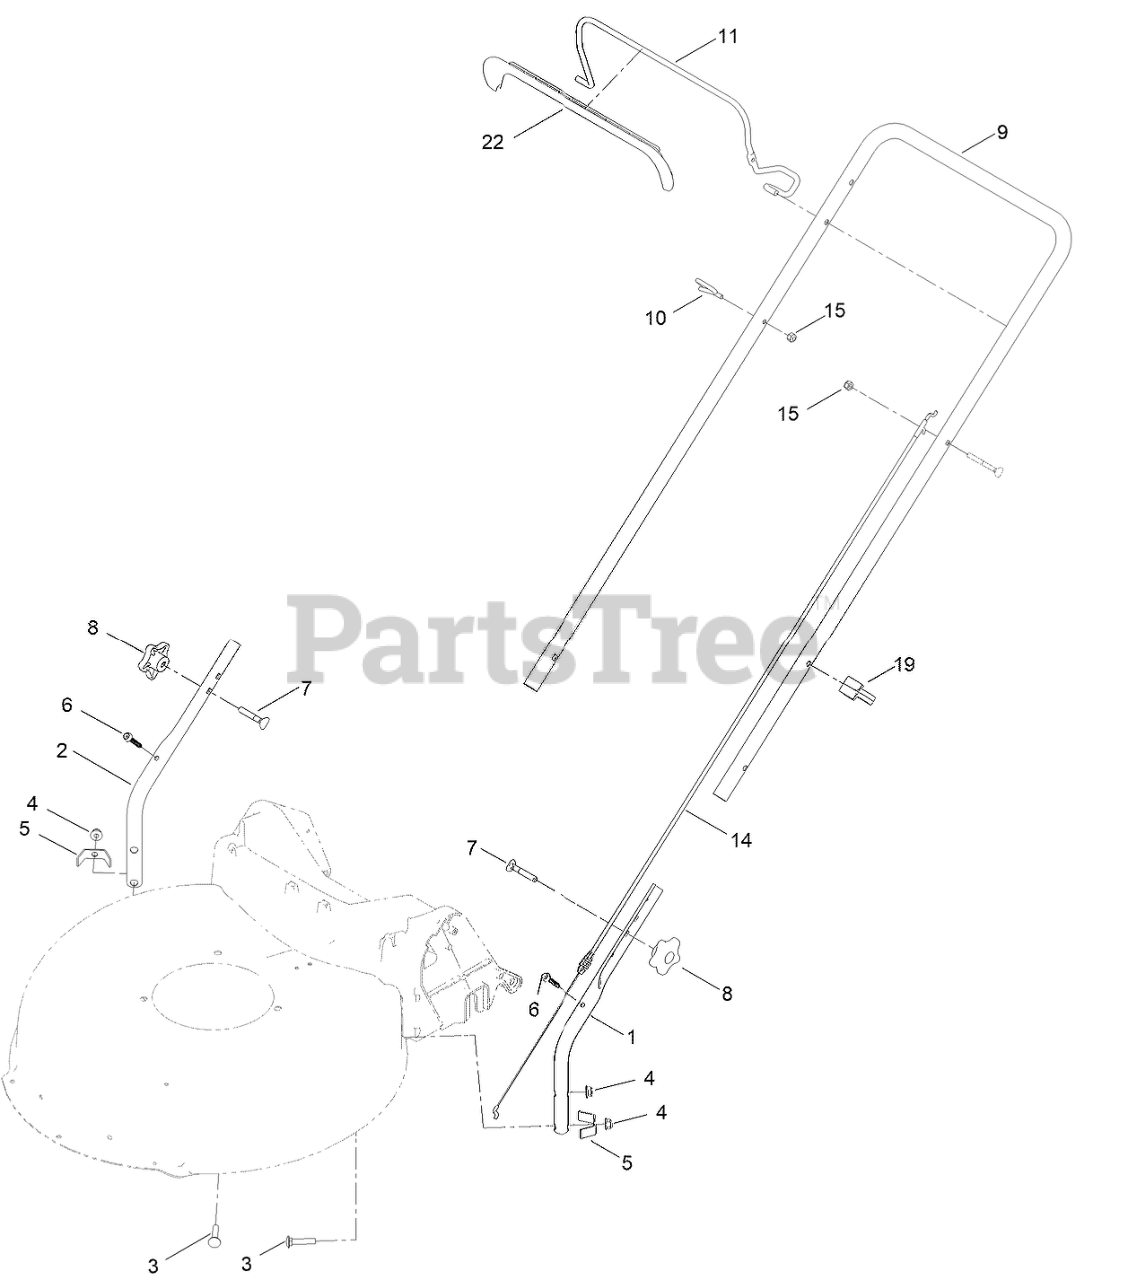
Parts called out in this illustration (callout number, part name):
1	HANDLE-LOWER, LH
2	HANDLE-LOWER, RH
3	BOLT-CARR
4	NUT-FLANGE, NI
5	BRACKET-CHUTE
6	SCREW-FLANGE, SERRATED
7	SCREW-HANDLE
8	KNOB-HANDLE
9	HANDLE-UPPER
10	GUIDE-ROPE
11	BAIL-BRAKE
14	CABLE-BRAKE, ENGINE
15	NUT-LOCK, NI
19	GUIDE-CABLE
22	COVER-BAIL
